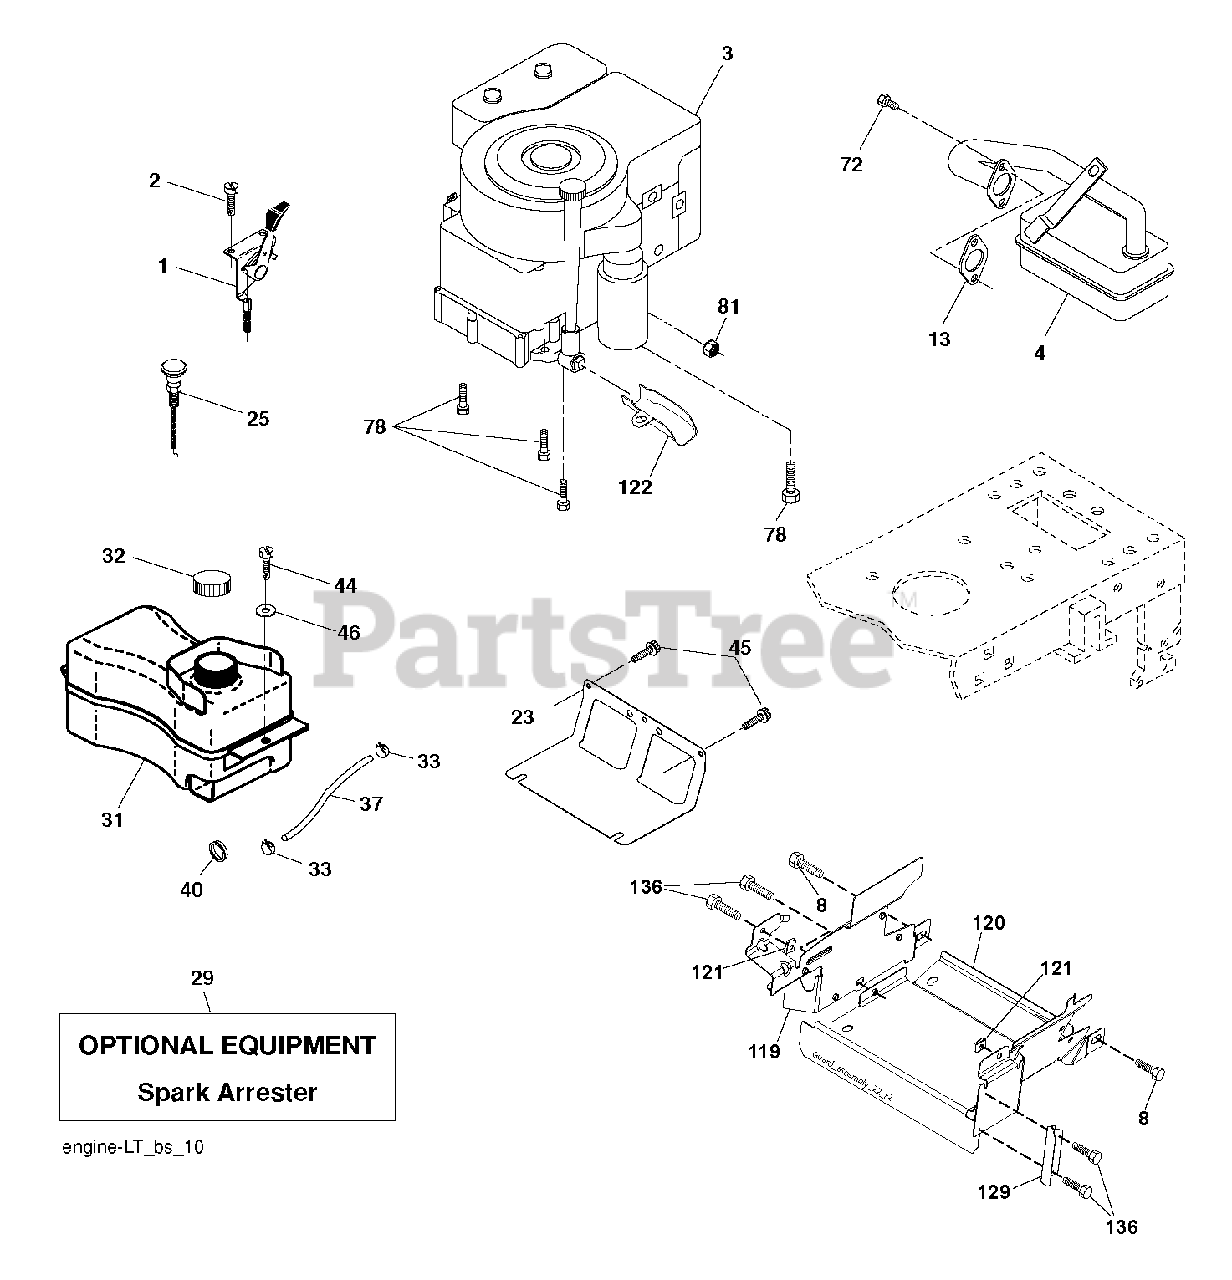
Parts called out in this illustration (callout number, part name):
1	CONTROL TH/CH FLAG
2	SCREW
4	MUFFLER.SINGLE.CYL.KOHL/B&S
8	BOLT, 5/16-18 X 1 3/4
13	REPL BY 532 27 22-93
23	SHEILD.BROWNING.DBR.GUARD
29	ARRESTER SPARK (OPTIONAL)
32	CAP ASM.FUEL.2.25"FR.
33	HOSE CLAMP
37	LINE.FUEL.20
40	GROMMET T
44	SCREW HEXWSHR 1/4-20X3/4
45	SCREW, 3/8-16X3/4
72	SCREW.SOCKET HD.5/16-1
78	SCREW.3/8-16
81	NUT
122	EXTENSION DRAIN OIL
136	SCREW.1/4-20X5/8
